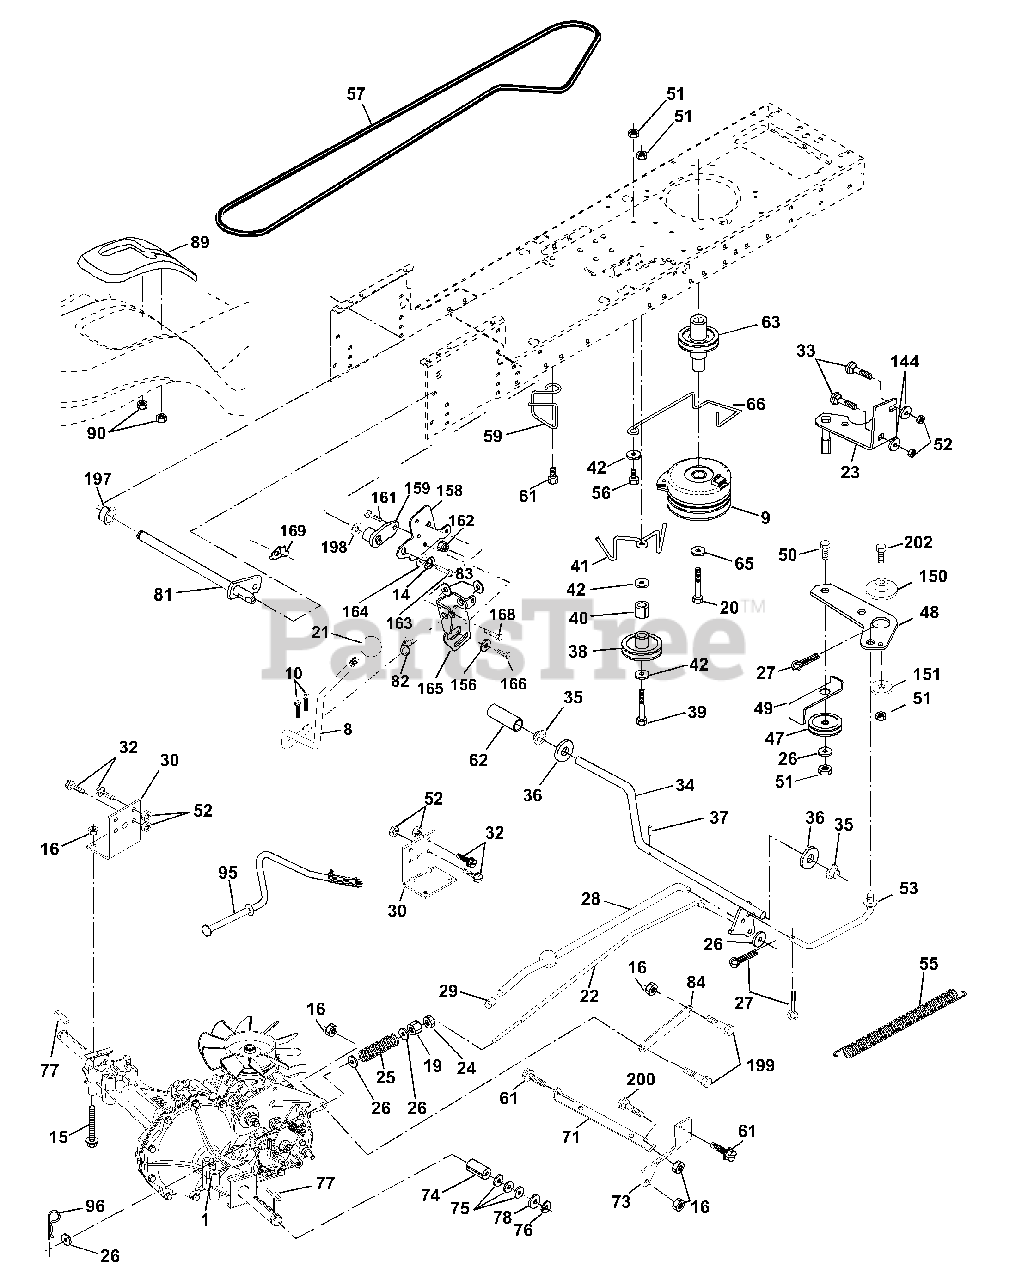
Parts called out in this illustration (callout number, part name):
8	Rod Shift Fender Adjust STLT
9	Clutch Electric
10	Pin Cotter 1/8 x 1 CAD
14	Washer Lock Hvy Helical
15	Bolt Hex 5/16-18 Unc Flghd
16	Nut Lock Hex W/Ins. 5/16-18 Unc P
19	Nut Lock Hex W/Ins 3/8-16 Unc
20	Bolt, Hex 7/16-20 x 4-1/4 Ga. 5
21	Knob Deluxe 1/2-13 UNC BLK/BLK
22	Rod, Brake Hydro
23	Bracket Asm Mtg CL
24	Nut Hex Jam 3/8-16 UNC
25	Spring, Brake Rod
26	Washer
27	Pin Cotter 1/8 x 3/4 CAD.
28	Rod, Parking Brake
29	Cap,Parking Brake
30	Bracket, Transaxle
32	Bolt Hex Hd 5/16-18 Unc x 3/4
33	Bolt Carriage 5/16-18 UNC x 3/4
34	Shaft, Foot Pedal
35	Bearing, Nylon
37	Pin, Roll
38	Pulley, Idler, Flat
40	Spacer Split
41	Keeper, Belt Idler
42	Washer 13/32 x 13/16 x 12 Ga
47	Pulley, Idler, V-Groove Plastic
48	Bellcrank Clutch Grnd Drv STL
49	Retainer, Belt Style Spring
52	Nut Crown Lock 5/16-18
53	Link, Clutch
55	Spring, Return, Clutch
56	Bolt, Fin Hex 3/8-16 UNC x 1 1/4
57	V-Belt, Ground Drive
59	Keeper, Center Span
61	Screw 3/8-16 x 3/4
62	Cover, Pedal
63	Pulley, Engine
65	Washer Lock Hvy HLCL Spr 7/16
66	Keeper Belt Engine
71	Strap Torque Lh Hydro
73	Strap Torque Rh Hydro
74	Spacer, Axle
75	Washer 25/32 x 1-1/4 x 16 Ga.
77	Key, Square
78	Washer 25/32 x 1-5/8 x 16 Ga
81	Shaft Asm Cross Tapered
82	Spring Torsion T/A
83	Washer 17/32 x 3/4 x 16 Ga.
84	Link Transaxle
89	Console, Shift Hydro STLT
90	Nut Self-Thd Wsh-Hd 1/4 Zinc
95	Control Asm. Bypass Hydro
96	Retainer Spring 1" Zinc/Cad
144	Washer 11/32 x 5/8 x 16 Ga.
150	Bushing Bellcrank Grd Drive
151	Washer 13/32 x 2 x 10 Ga.
156	Washer Srrted 5/16ID x 1.125
158	Bracket Shift Mount
159	Hub Tapered Flange Shift Lt
161	Bolt Rdhd Sqnk 1/4-20 x 3/4 Gr 5
162	Nut Crownlock 1/4-20 Unc
163	Bolt Hex Fin 1/4-20 Unc x 1 Gr 5
164	Washer 5/8 x .281 x 10 Ga
165	Bracket Pivot Lever
166	Screw 5/16-18 x 5/8
168	Bolt Shoulder 5/16-18 x .561
169	Plate Fastening STLT/CRD
197	Nyliner Snap 5/8" ID
198	Washer Nyl 7/8 ID x .105 Hyd
199	Bolt Shoulder 5/16-18 Unc
200	Bolt Rdhd Sq Neck Unc
201	Screw Thdrol 3/8-16 x 3/4
